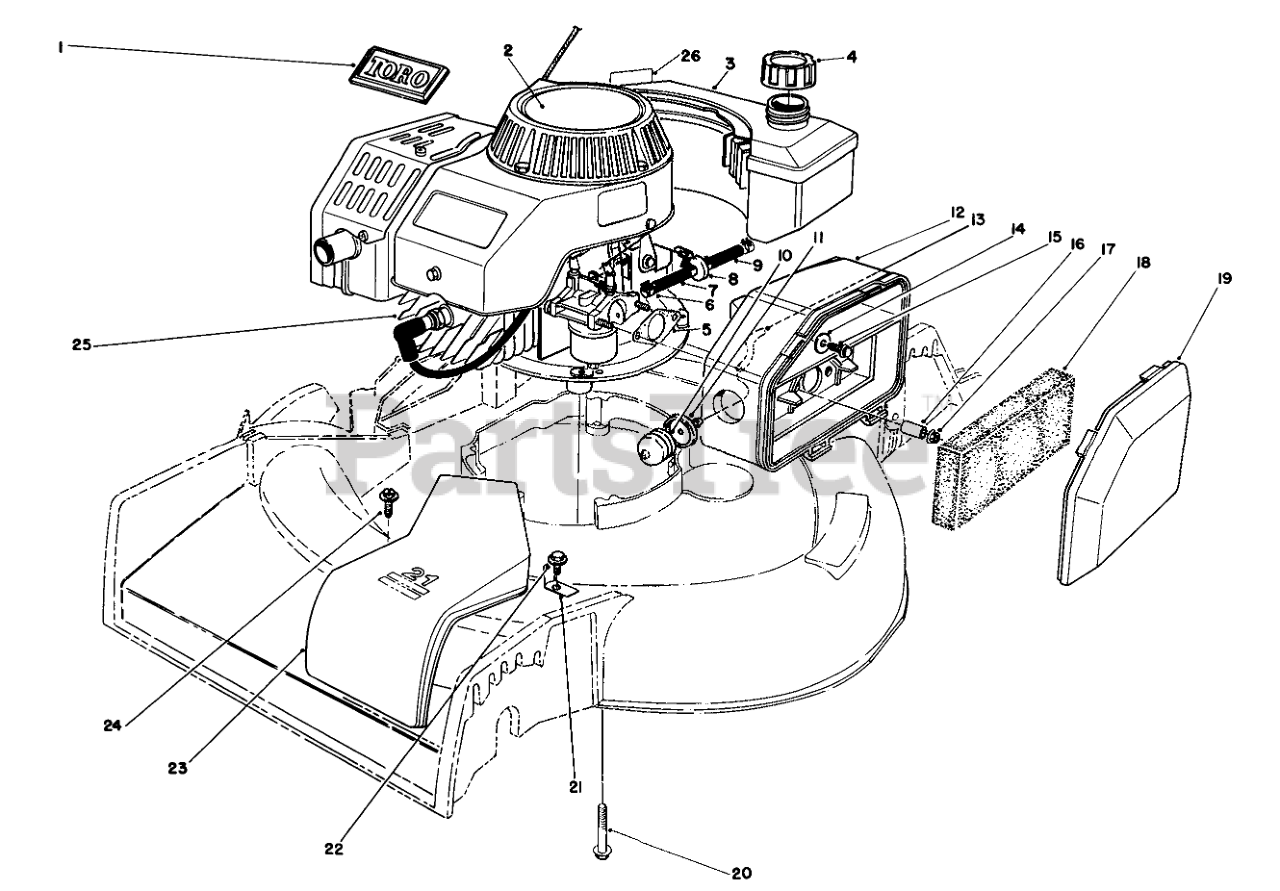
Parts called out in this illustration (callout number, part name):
1	TORO LOGO PLT
2	DECAL
3	FUEL TANK ASM
4	GAS CAP ASM
5	GASKET-AIR CLEANER
6	CLAMP-FUEL LINE
7	HOSE-FUEL
8	FILTER-FUEL
9	HOSE-FUEL
10	BULB-PRIMER
11	BODY-PRIMER
12	BODY-AIR CLEANER
13	HOSE-PRIMER
14	WASHER-FLAT
15	SCREW-HH
16	SPACER
18	ELEMENT-AIR CLEANER
19	COVER-AIR CLEANER
20	SCREW-HHF, WHIZ
21	BELT GUIDE
22	SCREW-HWHTF
23	BELT COVER 21" S D
24	SCREW
25	Engine
26	Decal-Maintenance
